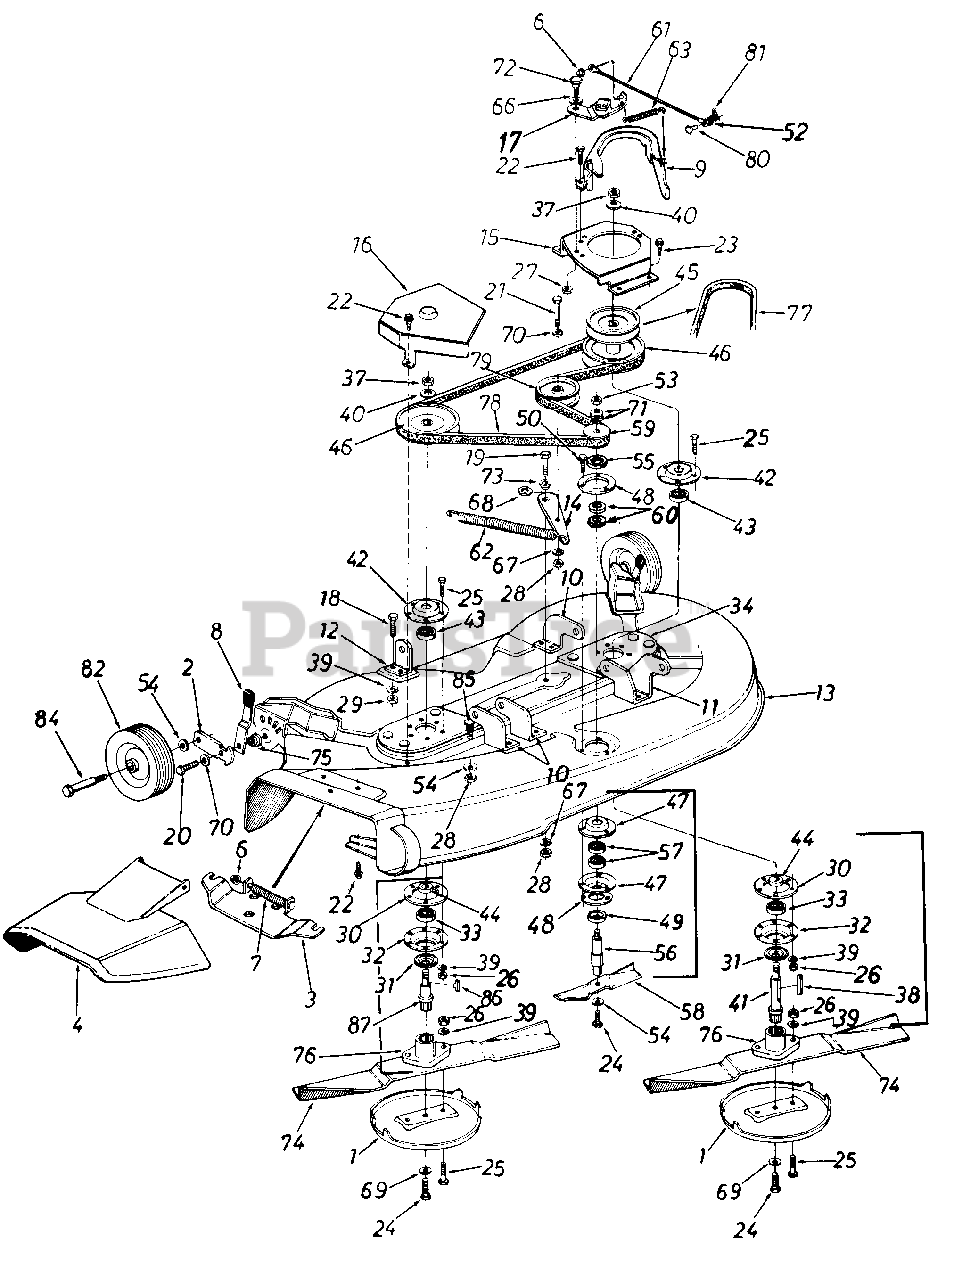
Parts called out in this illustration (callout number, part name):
1	Anti-Scalp Plate
2	Bar-Wheel Pivot
3	Adapter Plate
4	Chute Cover Ass'y.
6	Cap Speed Nut 1/4 Rod
7	Torsion Spring
8	Spring Lever Ass'y.
9	Belt Guard
12	Deck Hanger Bracket
13	44" Deck Ass'y.
14	Idler Bracket
15	Pulley Cover-L.H.
18	Hex Bolt 5/16-18 x .75" Lg.
19	Hex Bolt 3/8-24 x 1.00" Lg.
20	Hex Bolt 3/8-24 x 1.25" Lg.
21	Hex Bolt 3/8-24 x 1.50" Lg.*
22	Hex Wash. S-Tapp Scr. 1/4-20 x .50
23	Hex Wash. Hd. Tapp Scr. 5/16-18 x .75" Lg.
24	Hex Cent. L-Bolt 3/8-24 x .88" Lg.
25	Hex Bolt Special 5/16-24 x 1.0" Lg.
26	Hex Nut 5/16-24 Thd.
27	Hex Cent. L-Nut 5/16-18 Thd.
28	Hex Nut 3/8-24 Thd.
29	Hex Nut 5/16-18 Thd.
30	Reinforcement Plate
31	Bearing Shield
32	Open Brg. Housing 1.85 I.D.
33	Ball Brg. .787" I.D. x 1.85" O.D. x .551
34	Spindle Mounting Plate Ass'y.
37	Hex Jam Nut 5/8-18 Thd.
38	Sq. Key 3/16" x 2.25" Lg.
39	L-Wash. 5/16" I.D.
40	Bell-Wash. .630" I.D. x 1.25" O.D.
41	44" Deck Blade Spindle
42	Bearing Housing 1.85" I.D.
43	Ball Brg. .787" I.D. x 1.85" O.D. x .551
44	Spacer 1.0" O.D. x .790" I.D.
45	5/8 "V"-Pulley .79" I.D. x 5.75" O.D.
46	"V"-Pulley .79" I.D. x 6.50" O.D.
47	Bearing Housing 1-3/8" I.D.
48	Reinforcement Plate
49	Bearing Shield
50	Hex Wash. Hd. B-Tap Scr. 1/4 x .75" 9
52	Fl-Wash. .20" I.D. x .62" O.D.
53	Hex Jam Nut 1/2-20 Thd.
54	Bell-Wash. .400" I.D. x .88" O.D.
55	Fl-Wash. .635" I.D. x 1.04" O.D.
56	6.5" Blade Spindle
57	Ball Brg. .62" I.D. x 1.38" O.D. x .44
58	6.5" Blade
59	1/2" "V"-Puley Half .625" I.D. x 2.25" O.D.
60	Fl-Wash. 5/8" I.D. x 15/16" O.D.
61	Brake Cable 11.75" Lg.
62	Extension Spring .73" O.D. x 4.31 " Lg.
63	Ext. Spring .50" x 2.51" Lg.
66	Spring Wash. .445" I.D. x .75" O.D.
67	L-Wash. 3/8" I.D.
68	Spring Wash. .625" I.D. x .885" O.D.
69	L-Wash. 3/8" I.D.
70	Bell-Wash. .400" I.D. x 1.13" O.D.
71	Bell-Wash. .505" I.D. x 1.00" O.D.
72	Shld. Bolt .437" Dia. x .180
73	Shld. Spacer .625" I.D.
74	21" Blade
75	Shld. Spacer
76	Blade Adapter
77	"V"-Belt
78	"V"-Belt
79	Fl-Idler w/Flanges 3.50" O.D.
80	Clevis Pin 1/4" Dia. x .53" Lg.
81	Intern. Cotter Pin 5/16" Dia.
82	Deck Wheel 6.0" x 1.38
84	Shld. Bolt 3/8-16 x 1.41
85	Rib Neck Bolt
86	Sq. Key 3/16" x 3/16" x .75" Lg.
87	44" Deck Blade Spindle
